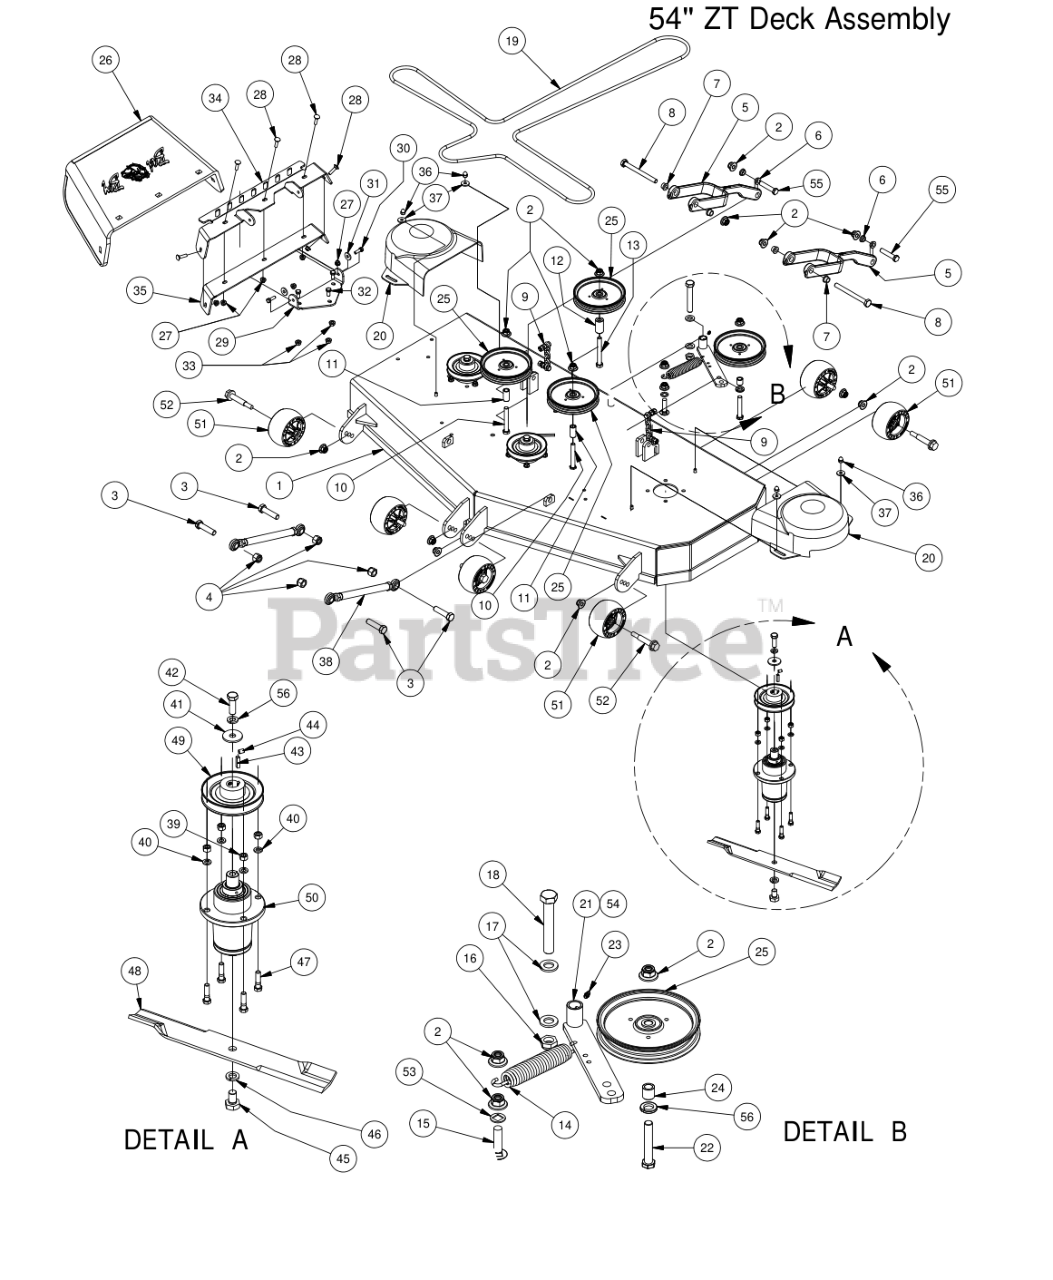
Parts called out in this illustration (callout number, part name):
1	ZT/Maverick 54" Deck
2	1/2-13 Nylon Flange Nut
3	5/8" x 2 1/2" Grade 5 Hex Bolt (Coarse)
4	5/8 Std NC Nylock Nut
5	Deck Arm Assembly
6	Flange Bushing For Lower Deck Arm
7	Flange Bushing For Upper Deck Arm
8	1/2" x 5 1/2" Bolt
9	Chain assembly
10	1/2 x 3 1/2 Flange Bolt Grade 8
11	.502 ID X.750 OD X 1.500 Long Spacer
12	1 3/4" Pulley Spacer
13	1/2" x 4" Bolt (Grade 8)
14	2009 Deck/Pump Idler Spring
15	1/2 x 2" Carriage Bolt
16	5/8-11 Nylon Insert Jam Half Nut
17	.630 ID Plastic Washer
18	5/8" x 4" Hex Bolt
19	B155.75 Deck Belt
20	2014 ZT Pulley Cover
21	Deck Idler
22	1/2-13 x GR 5 Hex Bolt Zinc
23	1/4" Press in Grease Fitting
24	Spacer 3/4 OD x 1/2 ID x 3\4 Length
25	5-3/4 Idler Pulley
26	Rubber Discharge Chute
27	5/16" Nylon Flange Nut
28	5/16" x 1 1/4" Carriage Bolt
29	Discharge Chute Hanger (Deck Mounted)
30	5/16" x 1" Bolt
31	.360 ID Plastic Washer
32	3/8" x 3/4" Hex Bolt
33	3/8" Flange Nut
34	60" Discharge Chute Upper Hanger
35	60" Lower Hanger
36	Acorn nut-pulley Cover
37	.360 ID Plastic Washer-Black
38	Turnbuckle (Top Link)
39	3/8" Hex Nut
40	3/8" Lock Washer
41	1/2 Belleville Washer
42	1/2"-20 x 1 1/2 - Grade 5 Fine Thread Bolt
43	1/4" x 1" Key
44	5/16 Set Screw
45	5/8" x 1 1/2" Grade 8 Hex Bolt (Fine)
46	5/8" Lock Washer
47	3/8" x 1 1/4" Hex Bolt
48	54" Deck Fusion Blade For Outlaw
49	5" Spindle Deck Pulley
50	Spindle Assembly
51	Anti-Scalp Rollers
52	Deck Wheel Bolt
53	.517 Square Hole Round Washer
54	Deck Idler Assembly (Components,2,21,22,23,24,25,56)
55	1/2" x 3" Hex Bolt
56	1/2" Lockwasher Zinc
